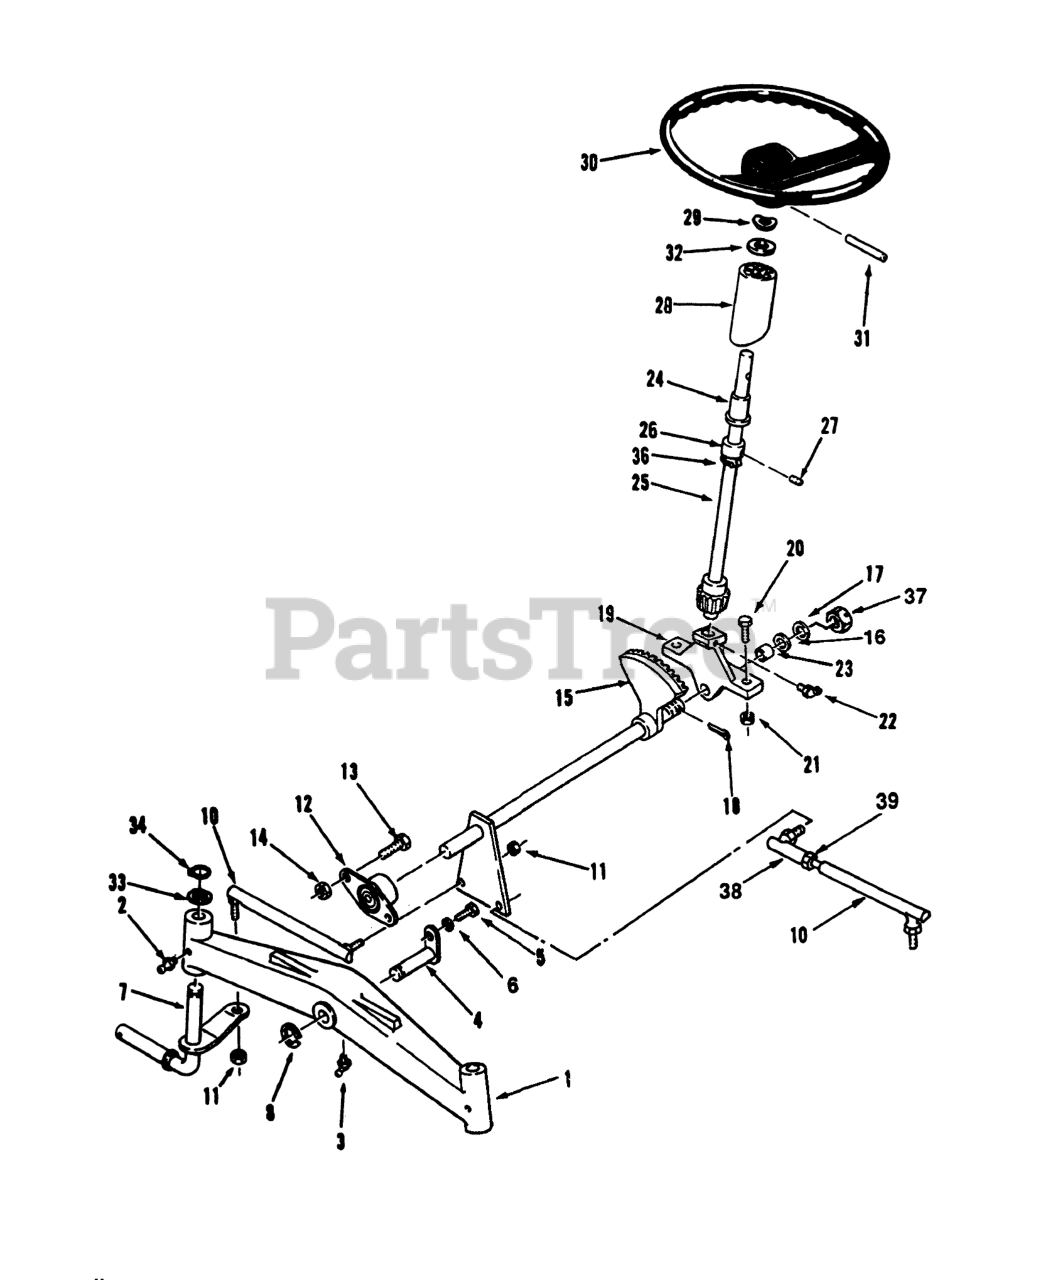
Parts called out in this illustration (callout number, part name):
1	AXLE-FRONT
2	Zerk
3	FITTING-GREASE
4	PIN AND PLATE ASM
5	SCREW-HH
6	WASHER-LOCK
7	LH SPINDLE ASM
8	E-RING
10	Tie Rod (Includes Item 38)
11	Nut
12	BEARING-FLANGED
13	SCREW-HH
14	NUT-LOCK, NI
15	Shaft
16	WASHER-SHIM
17	WASHER
18	PIN-COTTER
19	Support-Steering
20	SCREW-HH
21	NUT-HEX
22	FITTING-GREASE
23	BEARING-BRONZE
24	BEARING-FLANGED
25	Shaft-Upper Steering
26	Collar
27	SCREW-HSH
28	TUBE-STEERING
29	WASHER-BOWED
30	Steering Wheel
31	PIN-ROLL
32	WASHER-FLAT
33	WASHER
34	Snap Ring
36	RING-RETAINING
37	Nut-Slotted 3/4-16
38	BALL-JOINT
39	NUT-6
